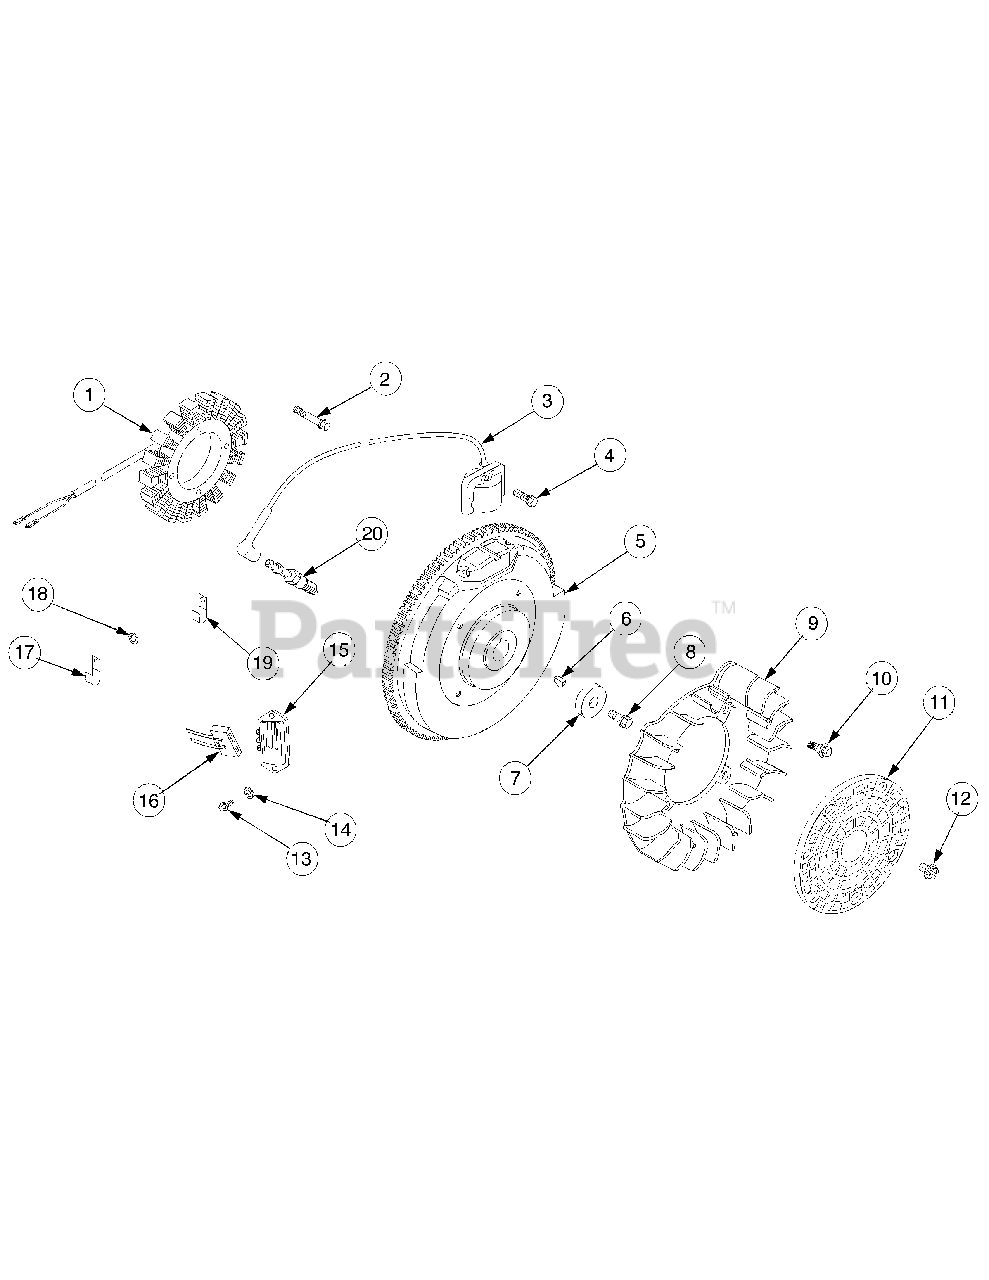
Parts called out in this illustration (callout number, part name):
1	Stator Kit, 15 Amp
2	Screw, Stator Mtg. M5 x .8 x 25
3	Module, Ignition
4	Screw, Module M5 x .8 x 20
5	Flywheel Assembly
7	Washer, Flat, 13/32
8	Screw, Flange M10x1.5 x 45
9	Fan
10	Bolt, Shoulder
11	Screen, Grass
13	Screw Phillips Hd., #11-16 x .875
14	Washer, Plain
15	Regulator - Rectifier
16	Connector, Regulator-Rectifier
17	Clip, Cable
18	Washer, Plain 1/4"
20	Spark Plug
